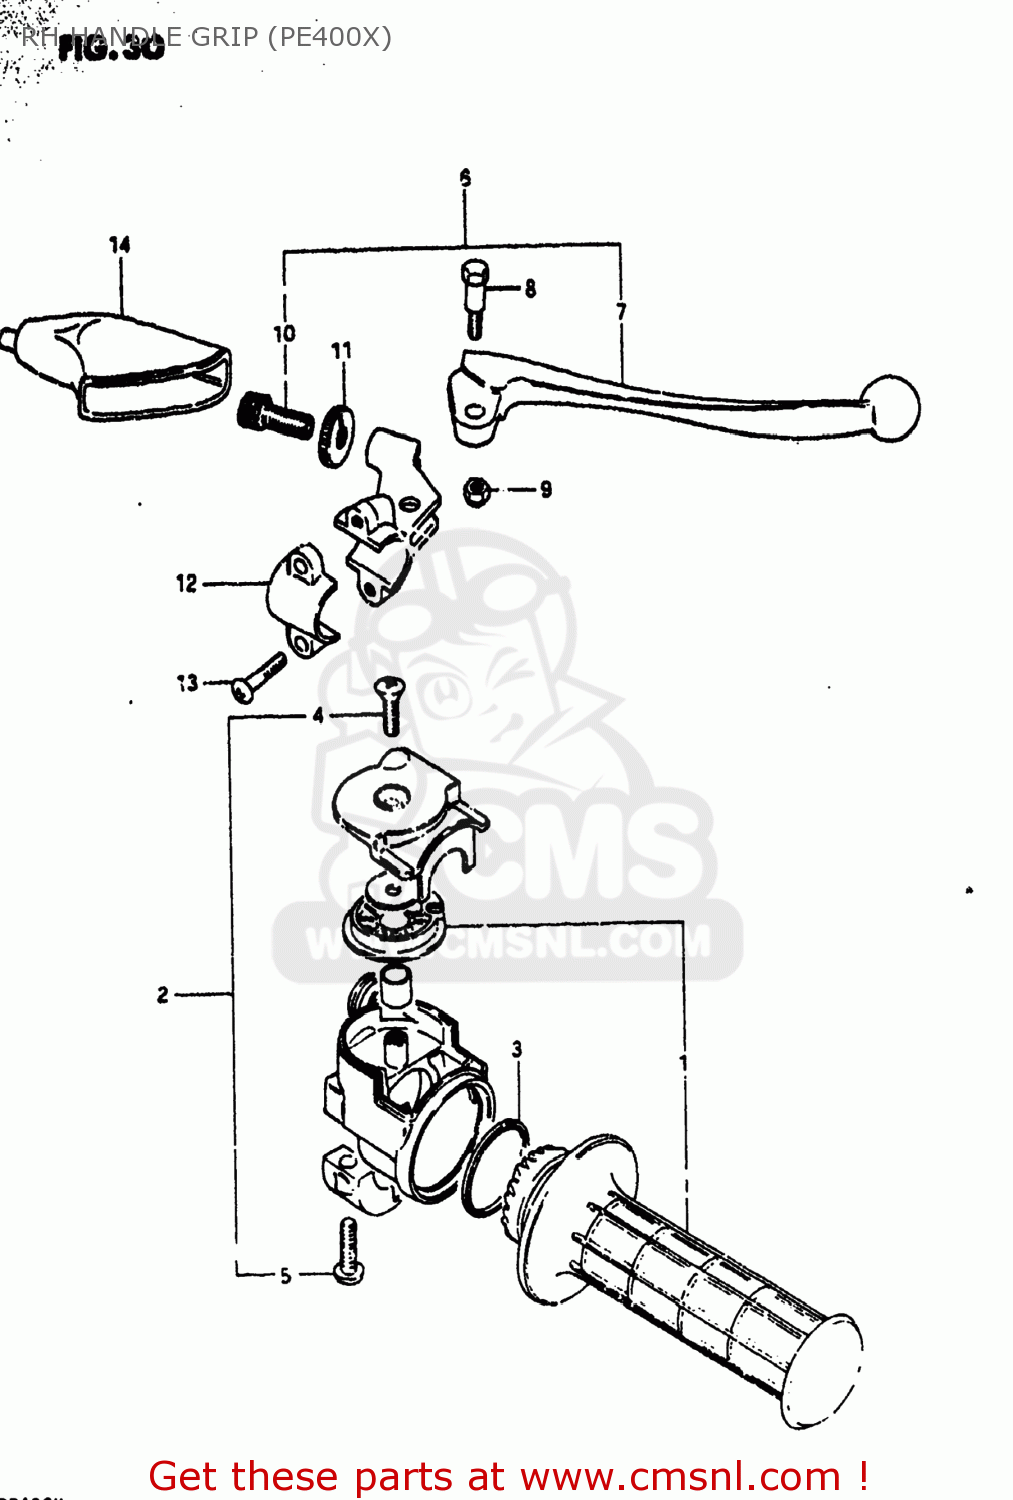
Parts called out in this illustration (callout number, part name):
1	GRIP SET,THROTTLE
2	CASE ASSY,THROTTLE
3	V-RING,THROTTLE GRIP
4	SCREW
5	SCREW
6	LEVER ASSEMBLY,BRAKE
7	LEVER,BRAKE
8	BOLT,LEVER
9	NUT 6MM
10	ADJUSTER,CABLE
11	NUT,CABLE ADJUSTER
12	BRACKET,LEVER
13	SCREW
14	COVER,CLUTCH LEVER
